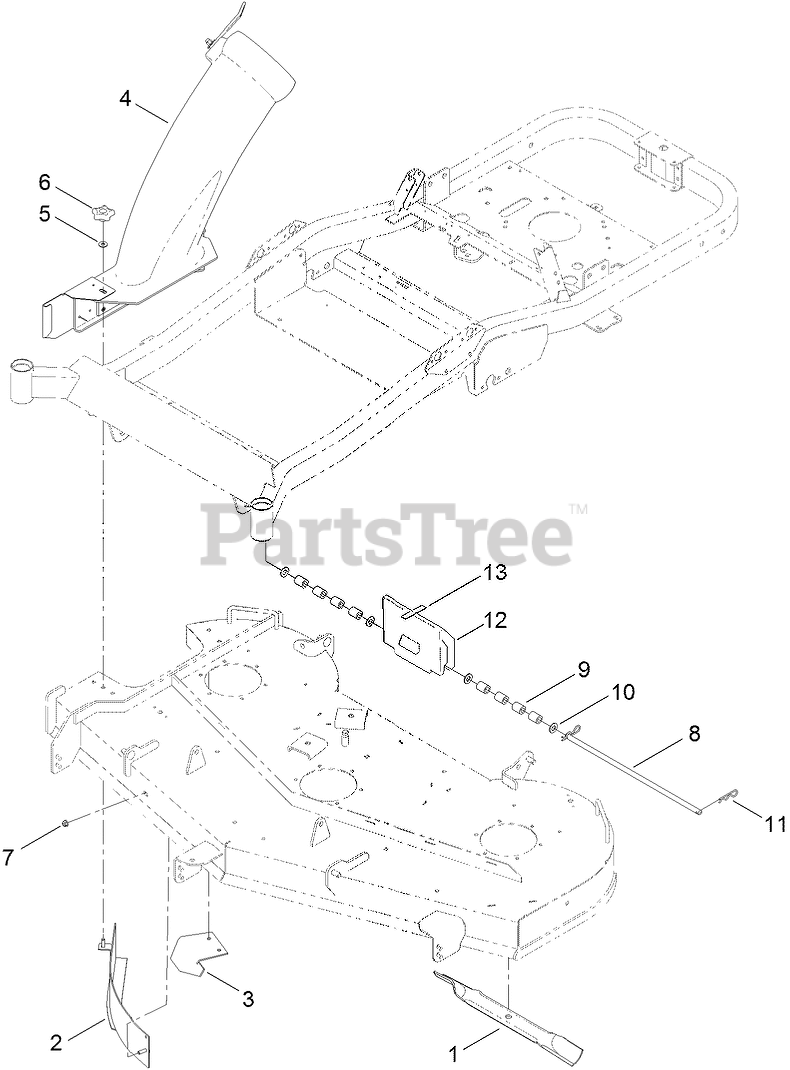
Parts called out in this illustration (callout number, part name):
1	BLADE-20.50 INCH
2	BAFFLE-BAGGER
3	BAFFLE-CUTOFF
4	BAGGER BOOT ASM
5	WASHER-FLAT
6	KNOB-LOCKING
7	NUT-HF, NI
8	ROD-DECK, PIVOT
9	SPACER-WHEEL
10	WASHER-FLAT
11	PIN-HAIR
12	WEIGHT-BAGGER
13	BUMPER-PAD
